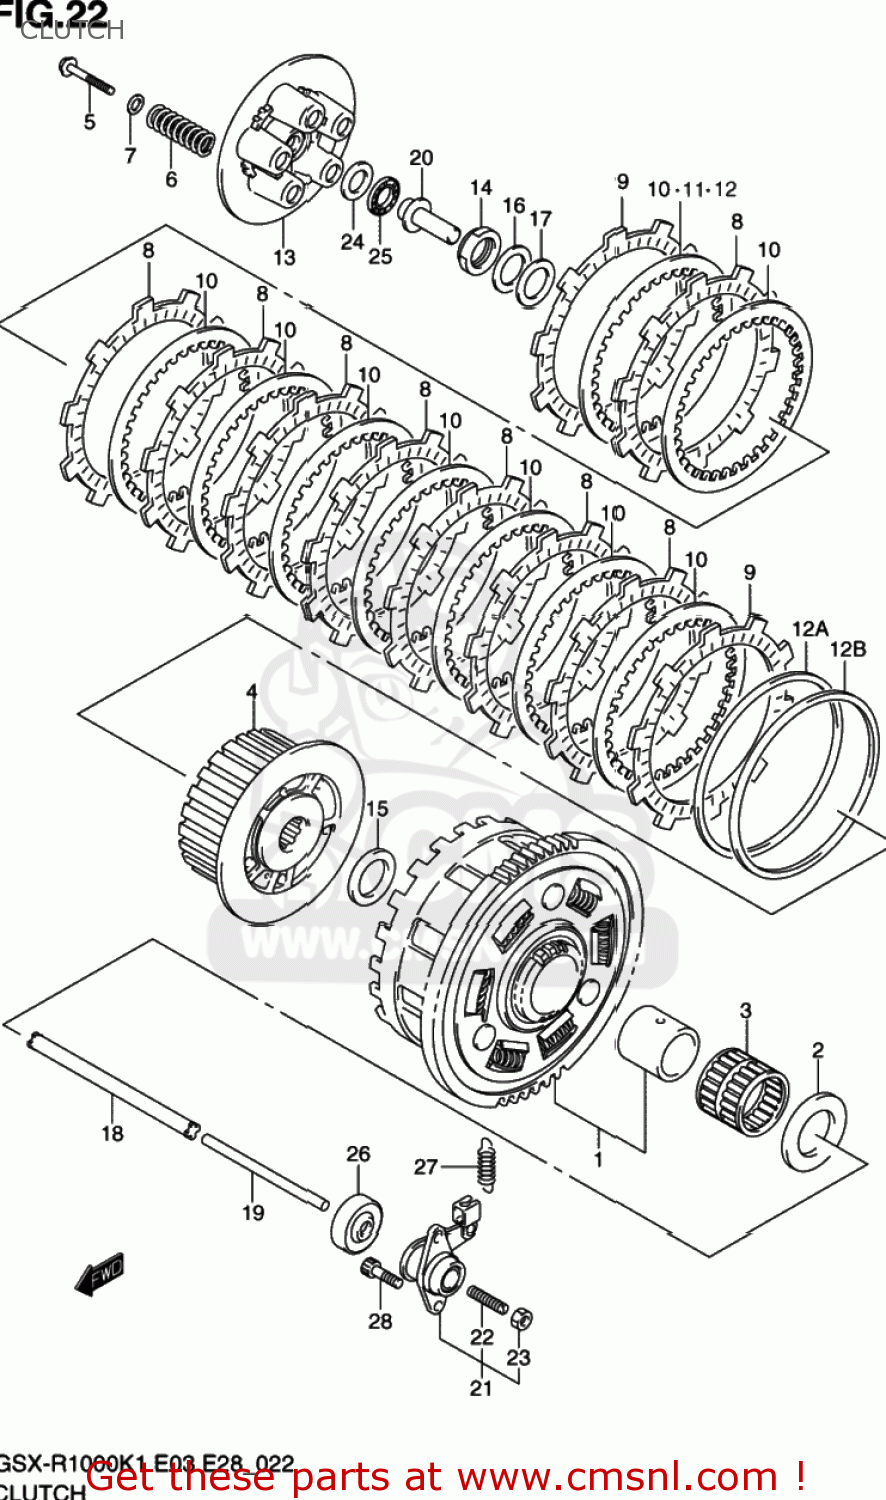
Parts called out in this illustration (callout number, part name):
1	GEAR ASSY,PRIM
2	WASHER(25X54X2.4)
3	BEARING(35X40X35.8)
4	HUB,CLUTCH SLEEVE
5	BOLT,CLUTCH SPRING
6	SPRING,CLUTCH
7	WASHER
8	PLATE,CLUTCH DRIVE NO.1 (NAS)
9	PLATE,CLUTCH DRIVE NO.2 (NAS)
10	PLATE,CLUTCH DRIVEN (NAS)
11	PLATE,CLUTCH DRIVEN NO.2(T:2.0 (NAS)
12	PLATE,CLUTCH DRIVE NO.3(T:2.6) (NAS)
12A	SEAT,CLUTCH PLATE WAVE WASHER
12B	WASHER,CLUTCH PLATE WAVE
13	DISC,CLUTCH PRESSURE
14	NUT
15	WASHER(25X50X2.5)
16	WASHER
17	SHIM(25X38X1)
18	ROD,CLUTCH PUSH,R
19	ROD,CLUTCH PUSH,L
20	PIECE,CLUTCH PUSH
21	SCREW ASSY,CLUTCH RELEASE
22	SCREW(6X25)
23	NUT
24	WASHER(15.5X28X1)
25	BEARING(15X28X2)
26	SEAL,OIL(6X34X10)
27	SPRING
28	BOLT
